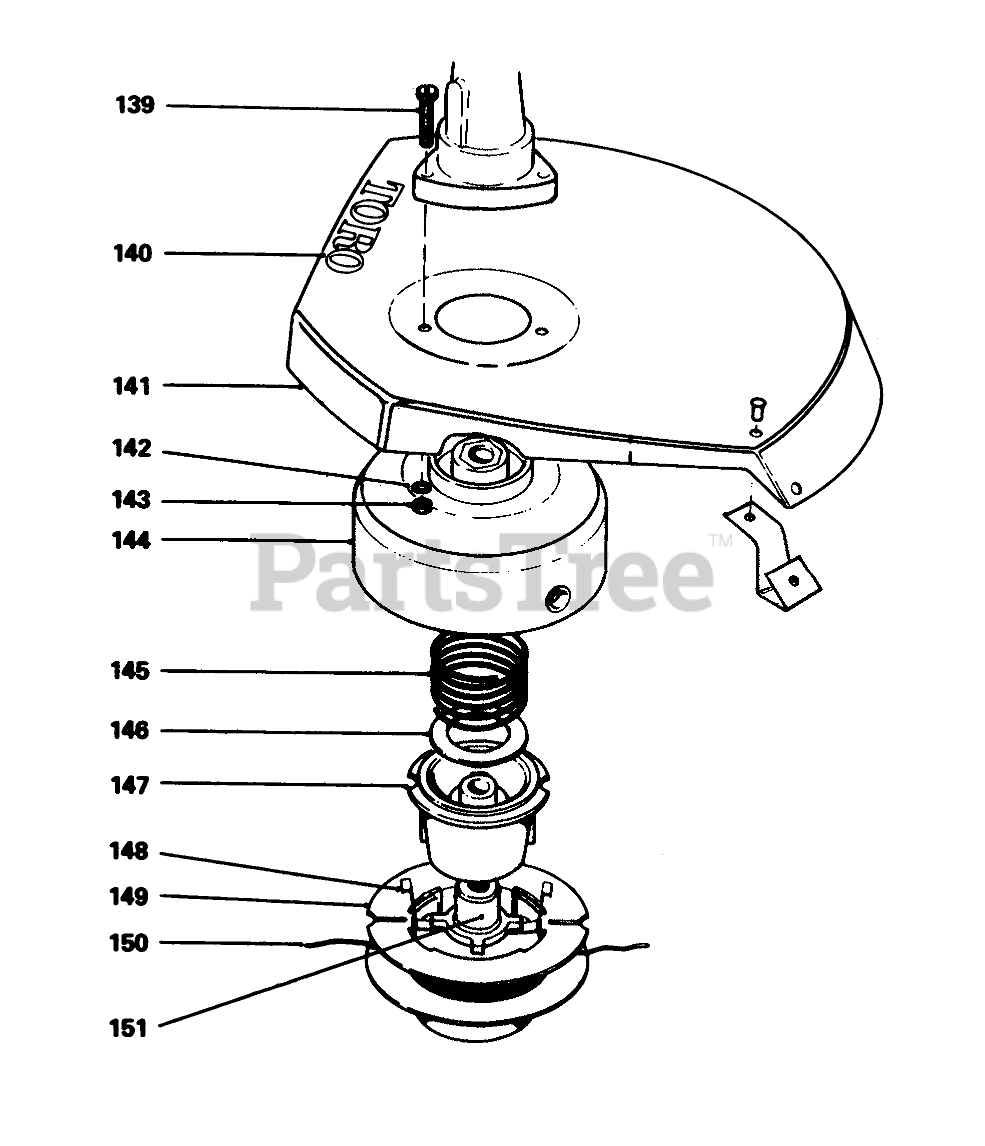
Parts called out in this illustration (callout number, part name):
139	SCREW-SHH
140	Decal, Toro
141	Shield w/cut-off Blade
142	WASHER-LOCK
143	NUT-HEX
144	Drum w/eyelet
145	SPRING
146	WASHER-FLAT
147	SPOOL CORE
148	SADDLE-SPOOL CAP
149	Empty SPooI
150	50-Coil.065" Cutting Line
151	LH DRIVER
